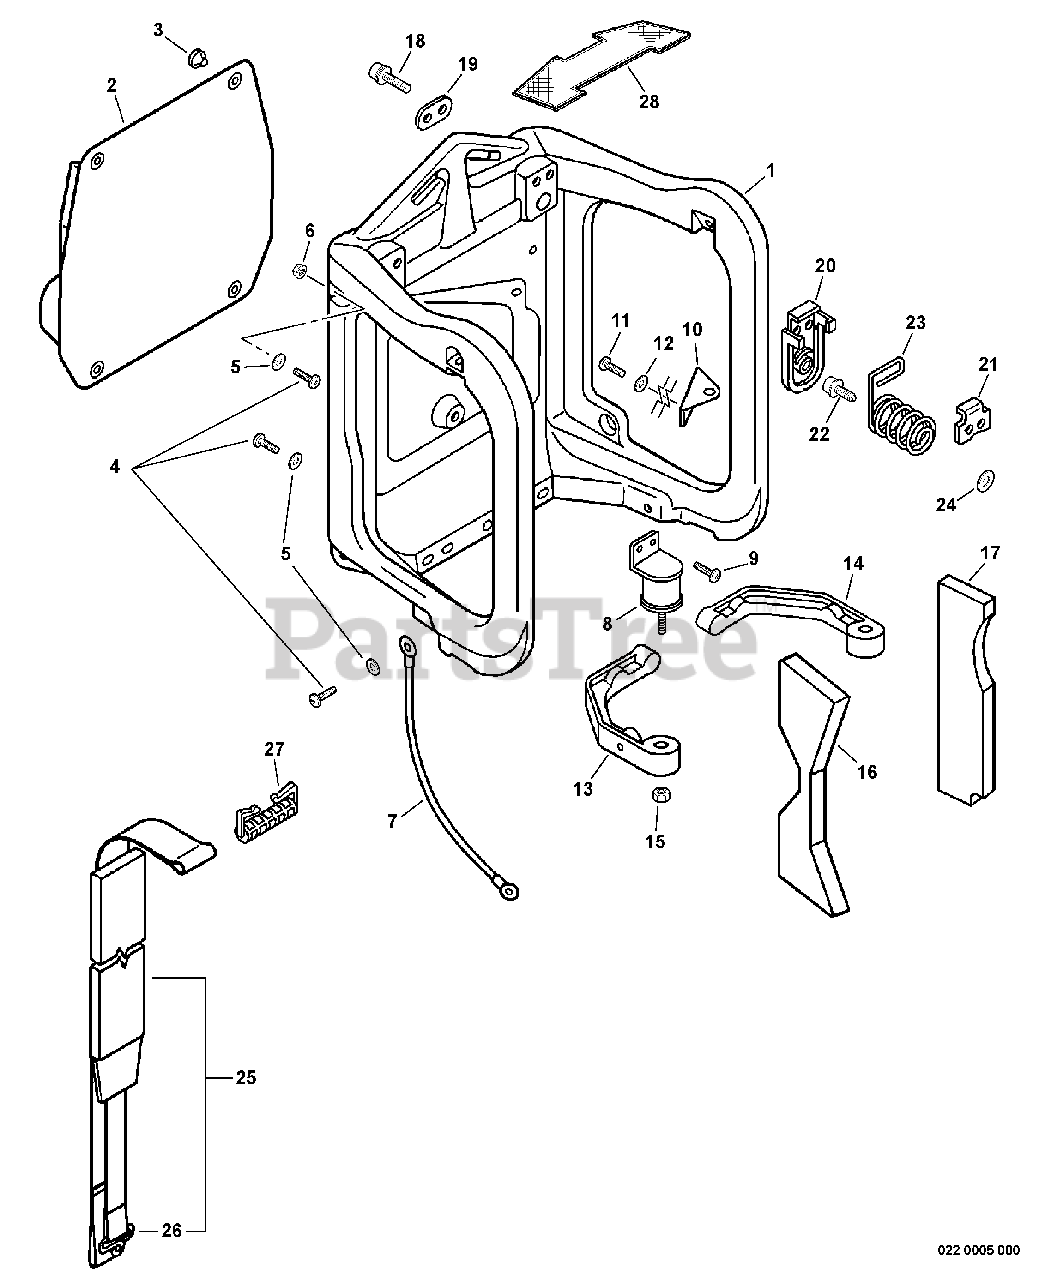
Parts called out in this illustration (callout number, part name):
1	FRAME, BACKPACK
2	CUSHION, BACKPACK
4	SCREW - 5X16 -- TAPPING
6	NUT - 5 -- FLANGE
7	LEAD - GROUND
8	CUSHION
9	SCREW - 5X16
10	BRACKET, HANGER
11	SCREW - 5X14
13	CONNECTOR, FRAME - LEFT
14	CONNECTOR, FRAME - RIGHT
15	NUT - 5 -- FLANGE
16	PAD, FOAM - LEFT
17	PAD, FOAM - RIGHT
18	SCREW - 5X20
20	BRACKET, SPRING
21	RETAINER
22	SCREW - 5X20
24	WASHER - 5
25	BACKPACK STRAP ASSY
27	RETAINER, HARNESS
28	COVER, DUST
